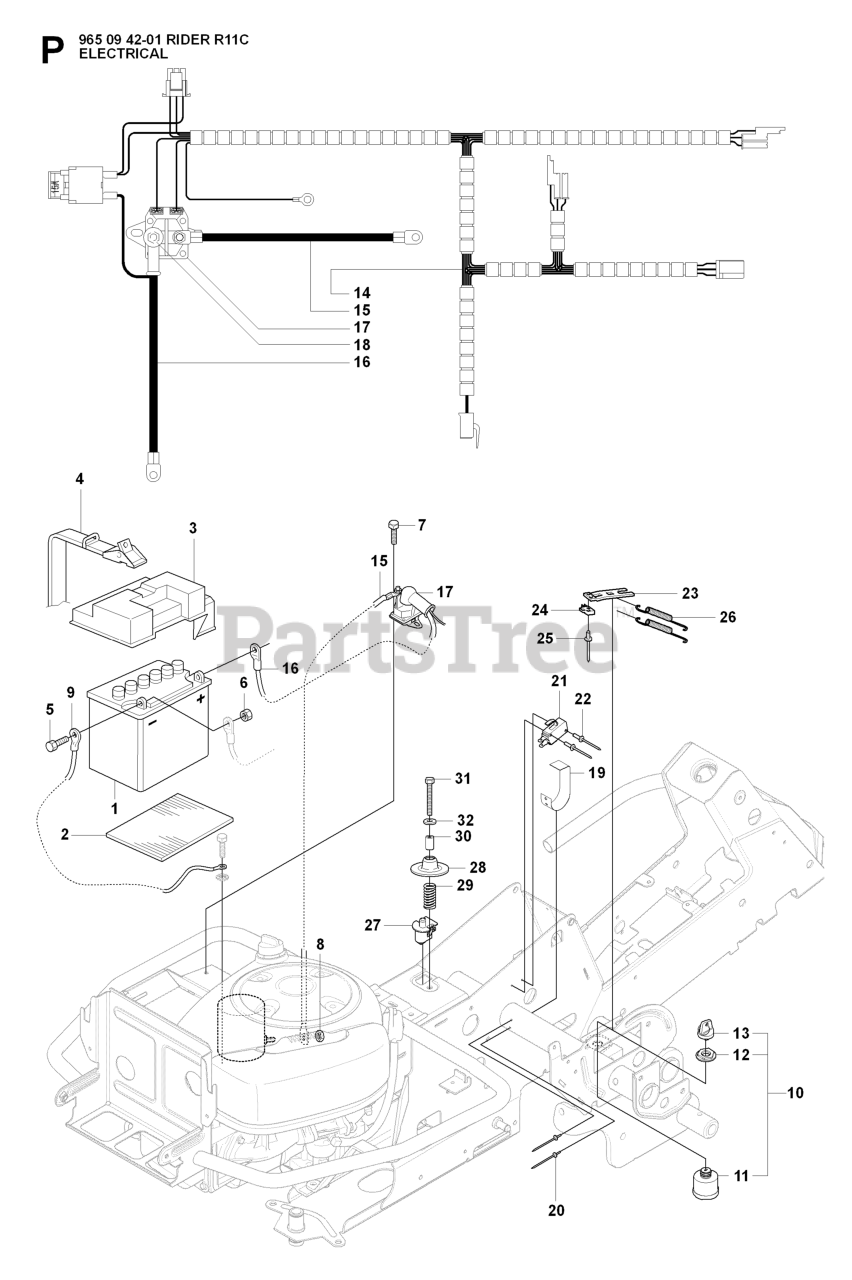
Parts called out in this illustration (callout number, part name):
1	BATTERY - DRY
10	IGNITION SWITCH
11	IGNITION SWITCH
13	IGNITION KEY
21	%BRAKER
24	%BRAKER
30	SPACER TUBE
31	SCREW
32	WASHER BRB 8.4X17
